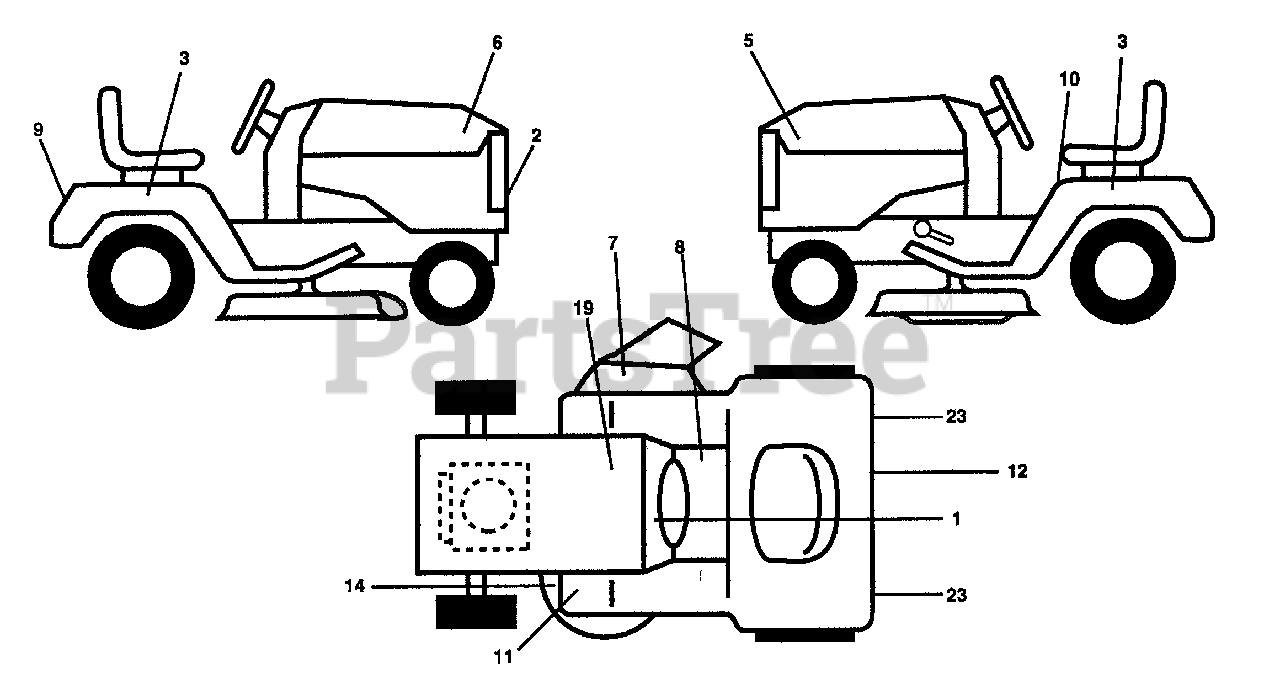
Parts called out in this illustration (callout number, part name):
1	Decal, Operating Instruction
2	Decal, Grille Husqvarna
3	Decal, Fender Automatic
5	Decal, Inst Hood LH GTH220 Hydro
6	Decal, Insrt Hood RH GTH220 Hydro
7	Decal, Warning Multi-Language
8	Decal, Brake Parking Saddle
9	Decal, Fender
10	Decal, Danger
11	Decal, Clutch/Brake
12	Decal, D-Bar Ctrl. Mvt Hyd YT/GT
14	Decal, V-Belt Schematic
19	Decal, Battery
23	Reflector, Taillight
